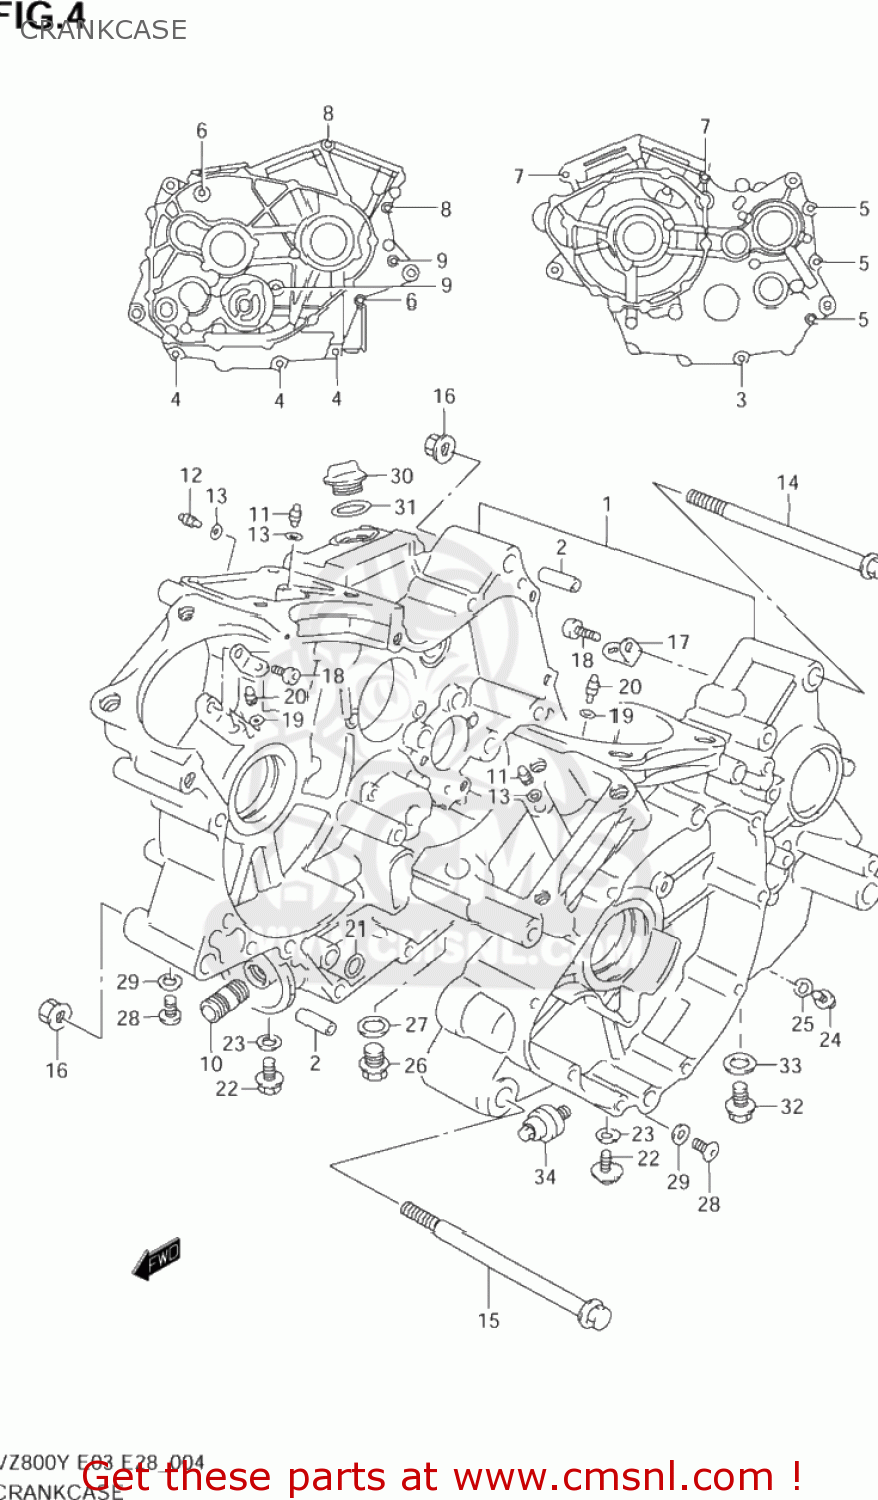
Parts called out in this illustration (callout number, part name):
1	CRANKCASE SET
2	PIN,CRANKCASE
3	BOLT
4	BOLT
5	BOLT
6	BOLT (8X70)
7	BOLT(8X105)
8	BOLT(8X160)
9	BOLT(8X80)
10	UNION,OIL STAND
11	JET,OIL GALLERY(18)
12	JET(8)
13	O RING(D:1.2,ID:4)
14	BOLT(10X143)
15	BOLT(10X155)
16	NUT
17	PLATE,PISTON COOLING JET
18	BOLT
19	O RING(D:1.2,ID:4)
20	JET,PISTON COOLING(0.8)
21	O RING(D:1.9,ID:12.6)
22	BOLT
23	GASKET(8.2X14X1).6 (NAS)
24	BOLT
25	GASKET(5.8X11X1.2) (NAS)
26	PLUG
27	GASKET(16X22X2) (NAS)
28	BOLT
29	GASKET(8.2X14X1).6 (NAS)
30	PLUG
31	O RING(D:3.1,ID:16.8)
32	PLUG,12X20
33	GASKET(12.1X16.2X3.7) (NAS)
34	SWITCH ASSY,OIL PRESSURE
